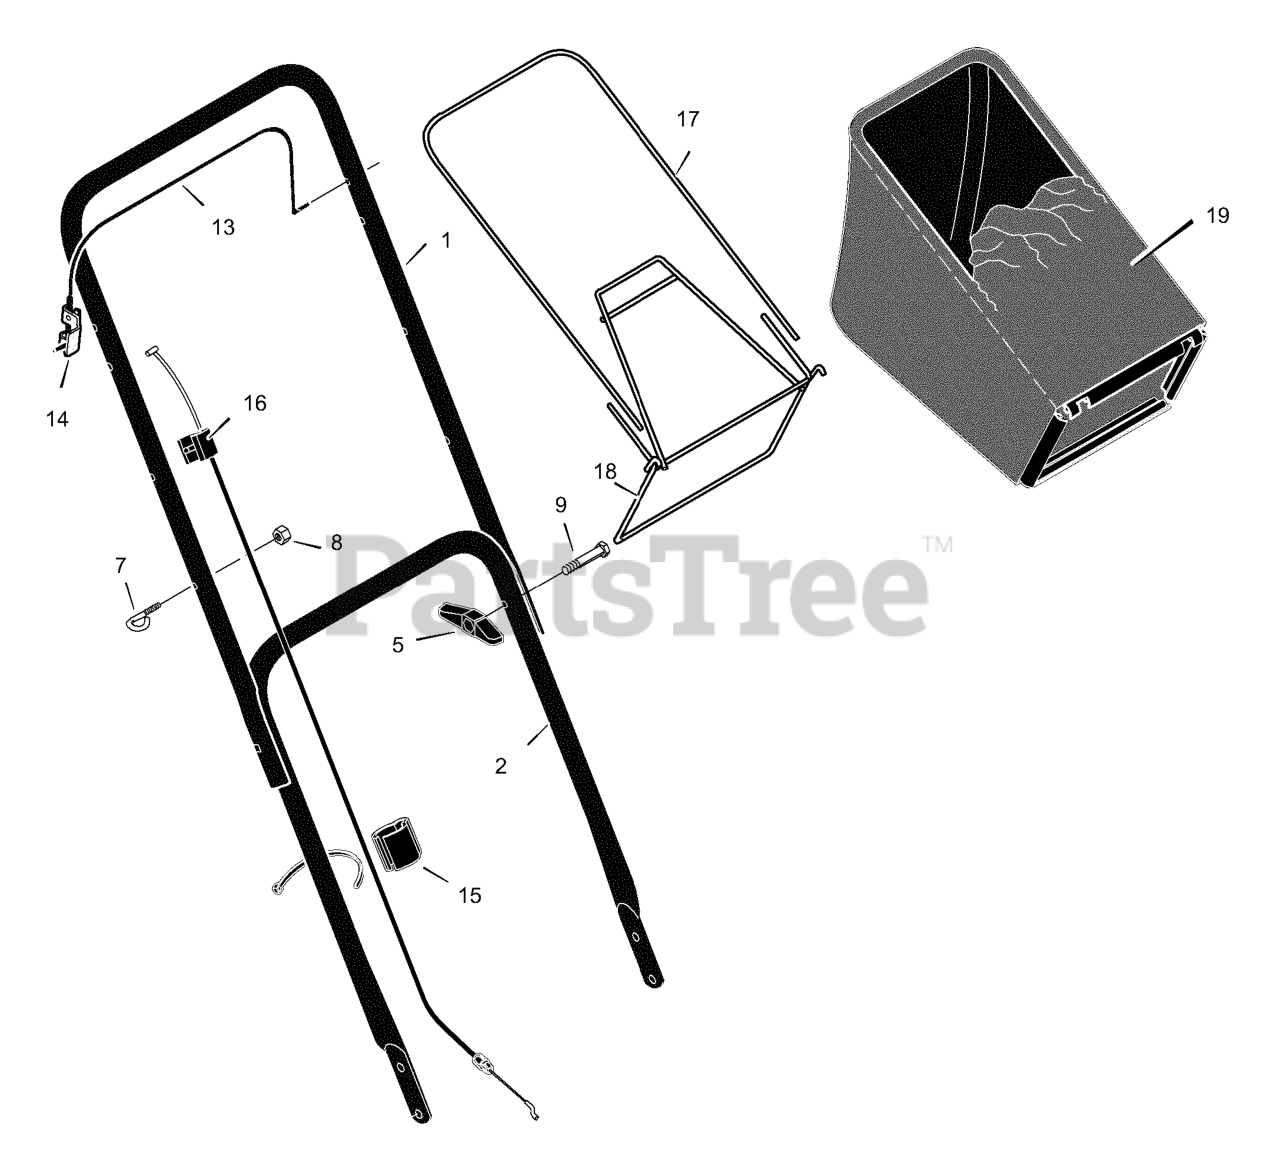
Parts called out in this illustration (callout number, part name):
1	Handle, Upper (Black)
2	Handle, Lower (Black)
5	Knob, Plastic
7	Guide, Rope
8	Locknut
13	Engine Stop Lever
14	Bracket, Stop Lever
15	Fastener, Cable
16	Engine Stop Cable
17	Frame, Top
18	Frame Assembly
19	Bag, Cloth - Black
